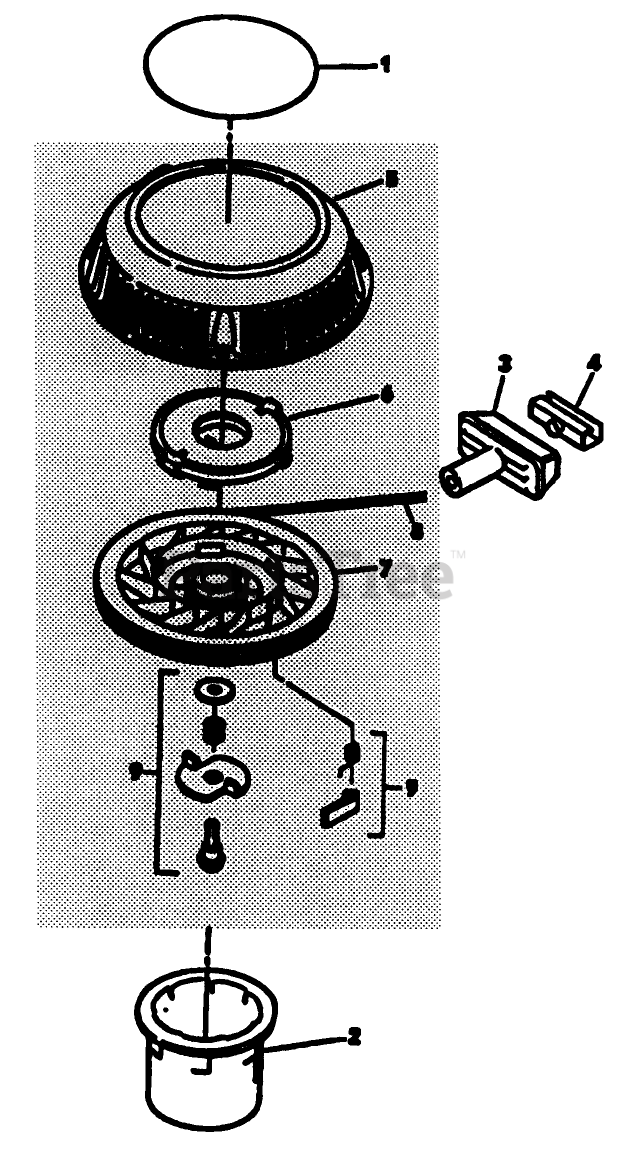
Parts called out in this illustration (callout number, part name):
2	HUB-STARTER E COMM.
4	CLIP-STARTER
5	STARTER HOUSING & SHAFT
7	PULLEY
9	DOG KIT
